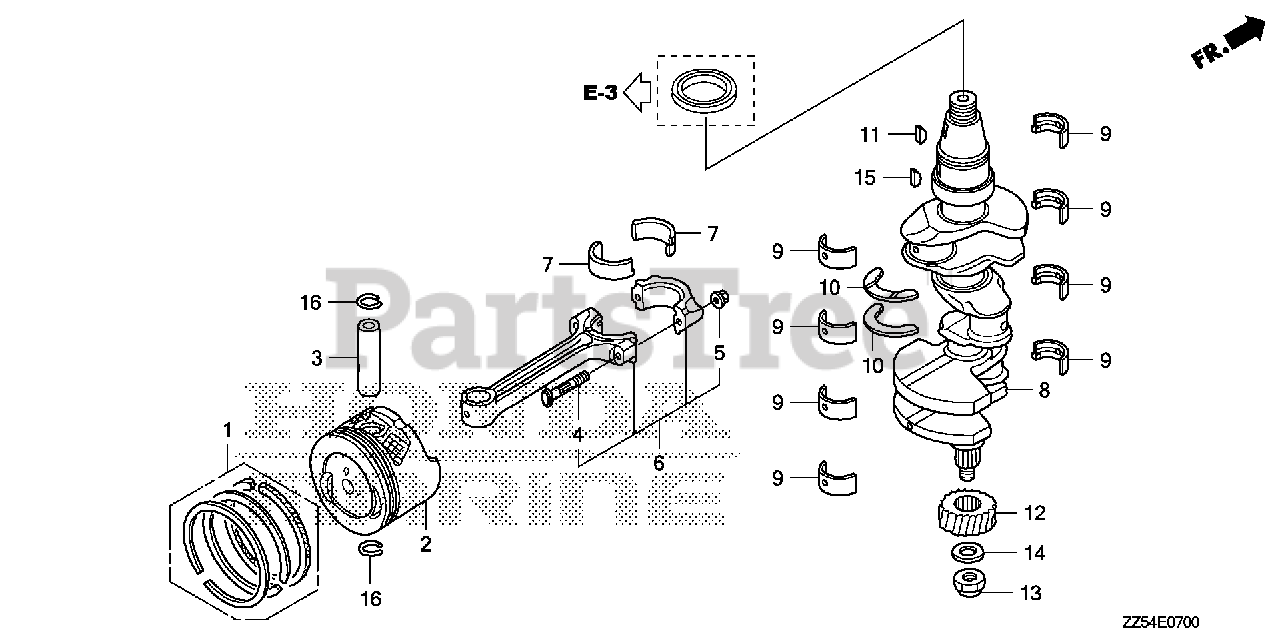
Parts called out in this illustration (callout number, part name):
1	RING SET, PISTON
1	RING SET, PISTON (OS 0.25)
2	PISTON (STD)
2	PISTON (OS 0.25)
3	PIN, PISTON
4	BOLT, CONNECTING ROD
5	NUT, CONNECTING ROD
6	ROD, CONNECTING
7	BEARING A, CONNECTING ROD (BLUE) (DAIDO)
7	BEARING B, CONNECTING ROD (BLACK) (DAIDO)
7	BEARING C, CONNECTING ROD (BROWN) (DAIDO)
7	BEARING D, CONNECTING ROD (GREEN) (DAIDO)
7	BEARING E, CONNECTING ROD (YELLOW) (DAIDO)
7	BEARING F, CONNECTING ROD (PINK) (DAIDO)
7	BEARING G, CONNECTING ROD (RED) (DAIDO)
8	CRANKSHAFT
9	BEARING A, MAIN (BLUE) (DAIDO)
9	BEARING B, MAIN (BLACK) (DAIDO)
9	BEARING C, MAIN (BROWN) (DAIDO)
9	BEARING D, MAIN (GREEN) (DAIDO)
9	BEARING E, MAIN (YELLOW) (DAIDO)
9	BEARING F, MAIN (PINK) (DAIDO)
9	BEARING G, MAIN (RED) (DAIDO)
10	WASHER, THRUST
11	KEY, SPECIAL WOODRUFF (25X18)
12	GEAR A, PRIMARY DRIVE (26T) (WHITE)
12	GEAR B, PRIMARY DRIVE (26T) (BLUE)
12	GEAR C, PRIMARY DRIVE (26T) (YELLOW)
13	NUT, FLANGE (22MM)
14	WASHER (22MM)
15	KEY, WOODRUFF (25X14)
16	CLIP, PISTON PIN (18MM)
